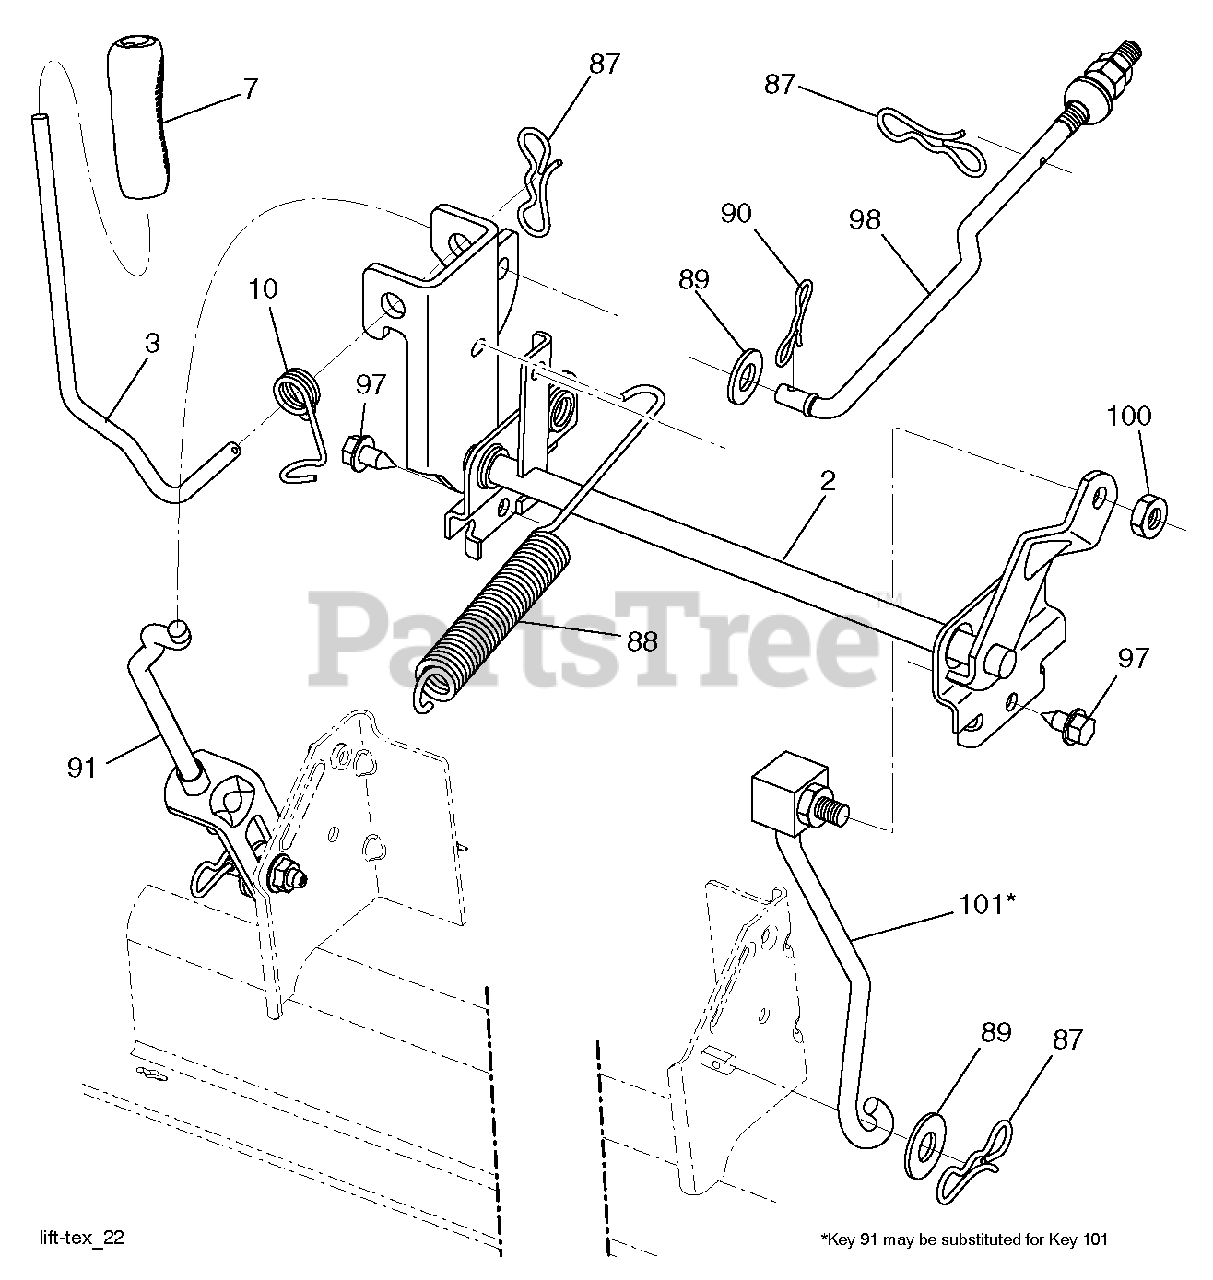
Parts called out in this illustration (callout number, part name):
2	SHAFT.ASM.CROSS.LIFT
3	LEVER.LIFT.HANDLE.LT
7	GRIP.HANDLE.LIFT.PVC.BLACK
10	SPRING.TORSION.LIFT.HANDLE
87	PIN.COTTER.7/16.BOW TI.
88	SPRING.LIFT.ASSIST
89	WASHER.CLEAR.ZINC
90	PIN.COTTER.5/16.BOW TI
91	LINK.ASM.LIFT.REAR
97	SCREW, 3/8-16X3/4
98	LINK.ASM.SUSP.FRONT.MW
100	LOCKNUT
101	LINK.ASM.LIFT.FIXE.38/42/46"
